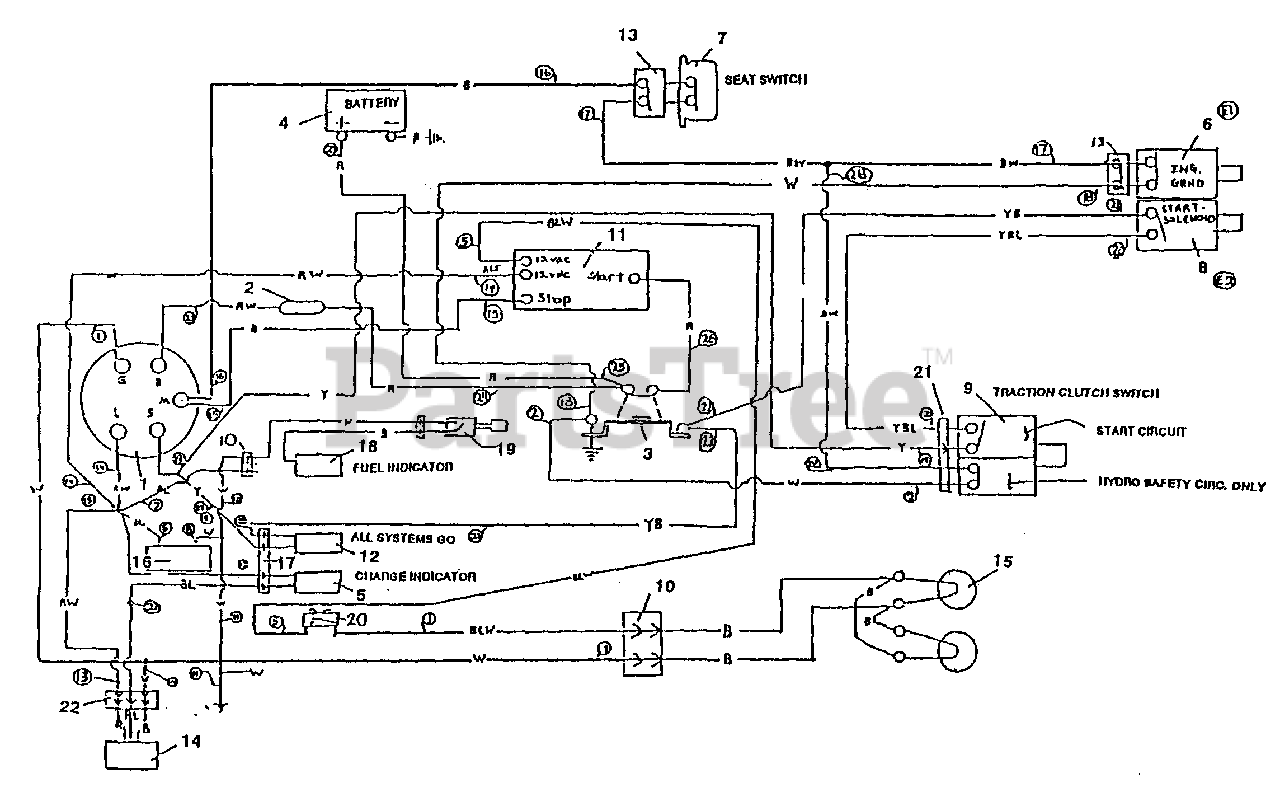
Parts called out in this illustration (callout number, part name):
1	IGNITION SWITCH
3	SOLENOID
4	BATTERY
5	ALTERNATOR LIGHT
6	DECK SWITCH (ign. grd, SAFETY CIRC.)
7	SEAT SWITCH (SAFETY CIRCUIT)
8	DECK SWITCH (START CIRCUIT)
9	CLUTCH SWITCH
10	PLUG-2 SOCKET
11	ENGINE
12	WARNING LIGHT, CLUTCH & MOWER
13	PLUG, SEAT SWITCH & DECK SWITCH
14	VOLTAGE DETECTOR
15	HEADLIGHTS
16	HOUR METER
17	PLUG-4 PIN LAMP HOLDER
18	WARNING LIGHT-FUEL LOW
19	LOW FUEL SWITCH
20	HEADLIGHT SWITCH
21	PLUG-CLUTCH SWITCH
22	PLUG-3 PIN (VOLTAGE DETECTOR)
